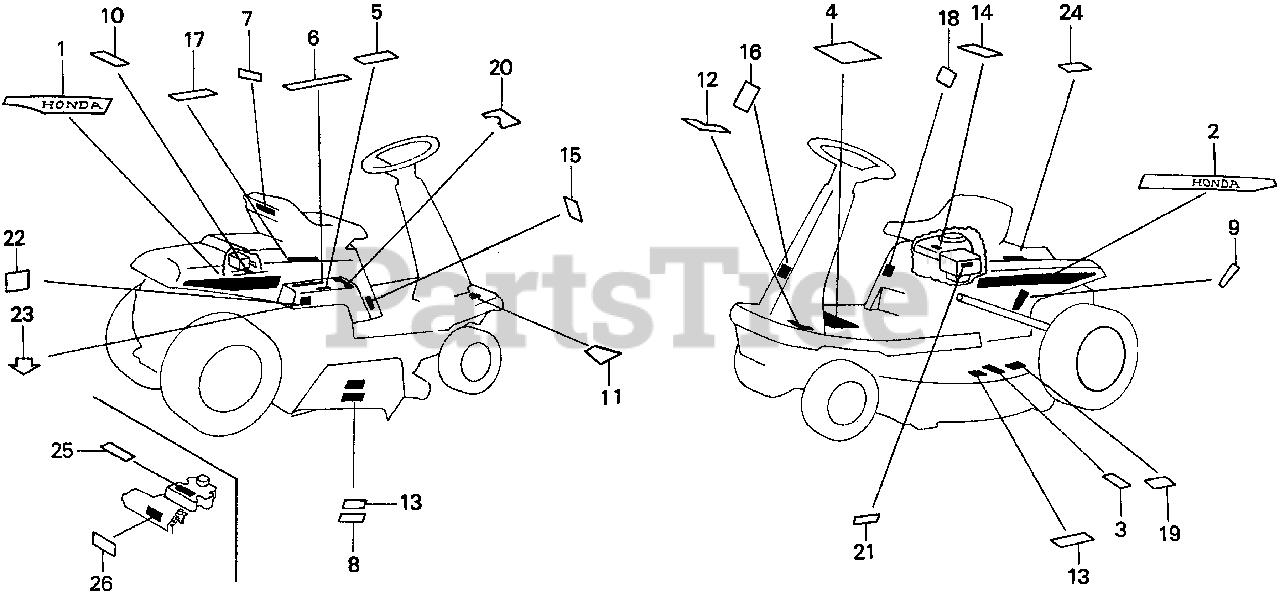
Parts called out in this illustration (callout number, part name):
1	STRIPE, R. SIDE
2	STRIPE, L. SIDE
3	MARK, INCH SIZE (30)
4	LABEL, OPERATION (ENGLISH)
5	MARK A, CHANGE (H.S.T.)
6	MARK B, CHANGE (H.S.T.)
7	MARK, SEAT
8	LABEL B, WARNING (ENGLISH)
9	MARK, INDICATOR (ENGLISH)
10	LABEL, MAIN FUSE (ENGLISH) (NOT AVAILABLE)
11	LABEL, BRAKE (ENGLISH)
12	MARK, P.T.O. CLUTCH (ENGLISH)
13	LABEL A, WARNING (ENGLISH)
14	LABEL, FUEL WARNING (B)(ENGLISH)
15	MARK, PARKING BRAKE (ENGLISH)
17	MARK, HYDROSTATIC
18	LABEL, PARKING BRAKE (ENGLISH)
19	LABEL D, CAUTION (ENGLISH)
20	MARK, ENGINE SWITCH (ENGLISH)
21	LABEL, AIR CLEANER CAUTION (ENGLISH)
22	MARK, EX. CAUTION (A)
23	MARK, EX. CAUTION (ENGLISH)
24	LABEL, OWNER'S MANUAL (ENGLISH)
25	LABEL, OIL RECOMMENDATION (ENGLISH)
26	LABEL, TRANSMISSION RELEASE LEVER (E)
